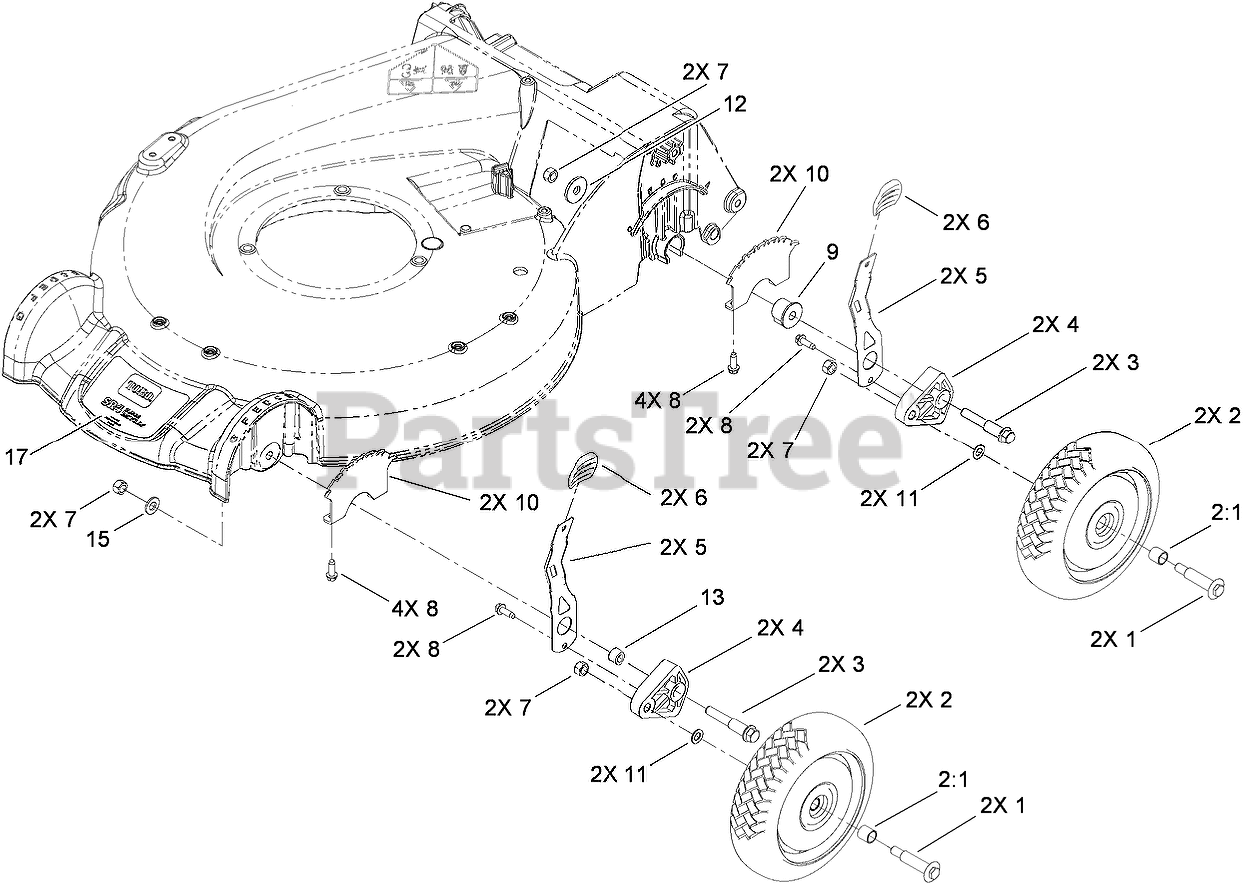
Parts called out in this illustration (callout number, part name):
1	BOLT-SHOULDER
2	WHEEL AND TIRE ASM
2:1	BUSHING
3	SCREW-SHOULDER
4	ARM-PIVOT
5	ARM-SPRING
6	Knob-Lever, HOC
8	SCREW-HWHTF
9	SPACER-HP
10	PLATE-HOC
11	WASHER
12	WASHER
13	SPACER-WHEEL
15	WASHER-FLAT
17	DECAL-SUPERCARE
